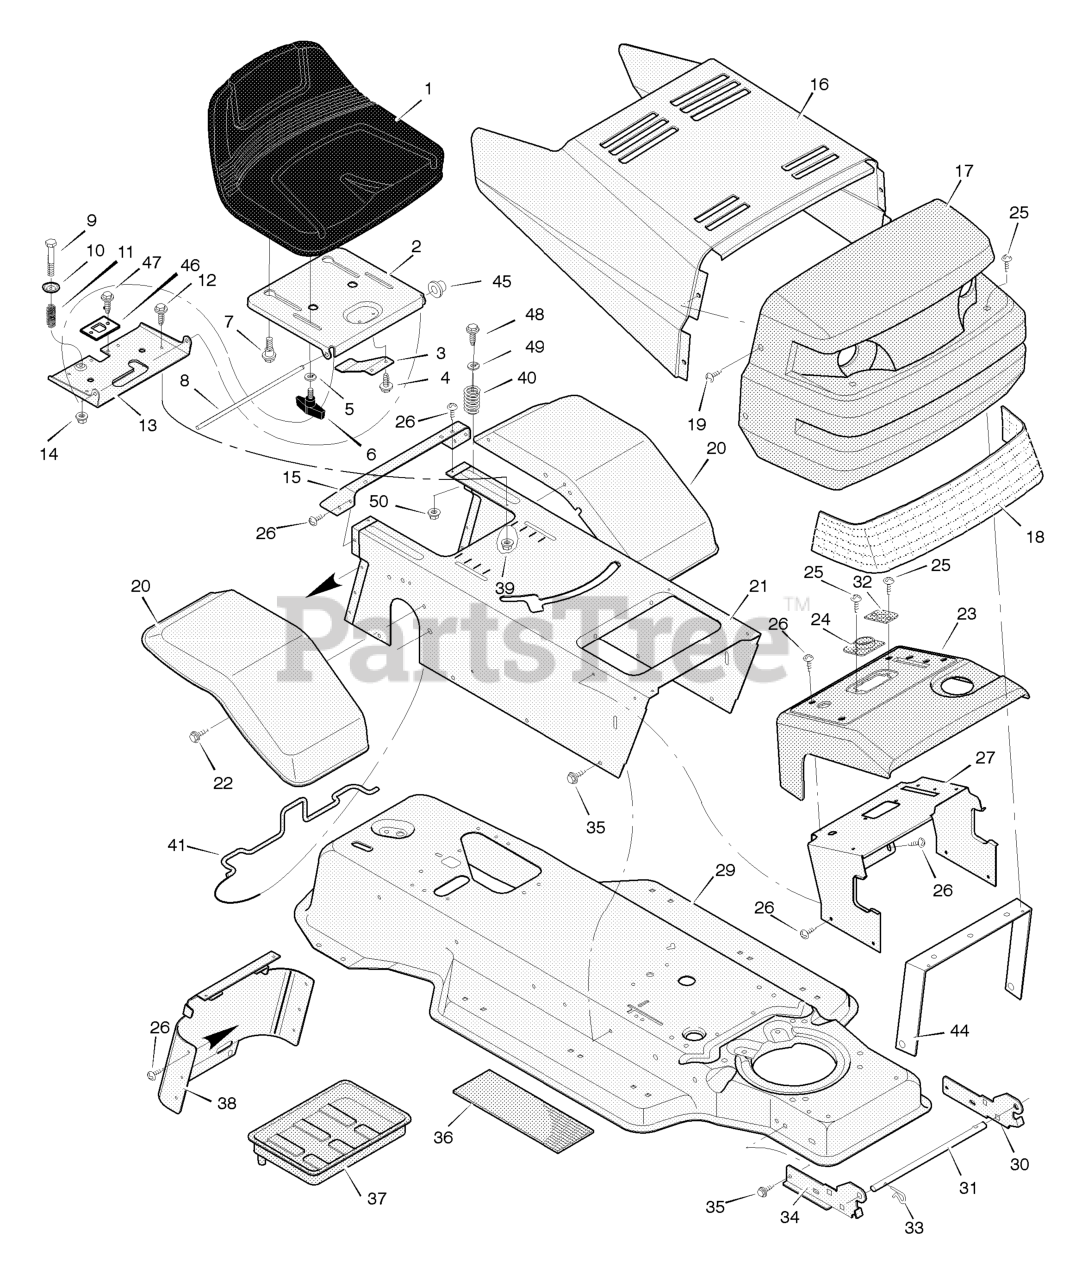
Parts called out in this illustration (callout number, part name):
1	Seat
2	Support, Seat
3	Spring, Seat
5	Washer
6	Bolt, Wing
8	Rod, Pivot
9	Bolt, Shoulder
11	Spring, Compression
12	Bolt, Hex
13	Bracket, Pivot
15	Fender, Apron
17	Grille Assembly
21	Console Assembly
23	Dash Panel
24	Bearing, Steering
26	Screw
27	Support, Dash
29	Frame Assembly
30	Bracket, Left Grille
31	Rod, Pivot
32	Bearing, PTO
33	Pin, Hair
34	Bracket, Right Grille
37	Tray, Battery
38	Cap, Console
39	Nut
40	Spring, Compression
41	Clamp, Battery
44	Brace, Grille
45	Cap, Push On
46	Plate Assembly, Switch
49	Washer
50	Nut
